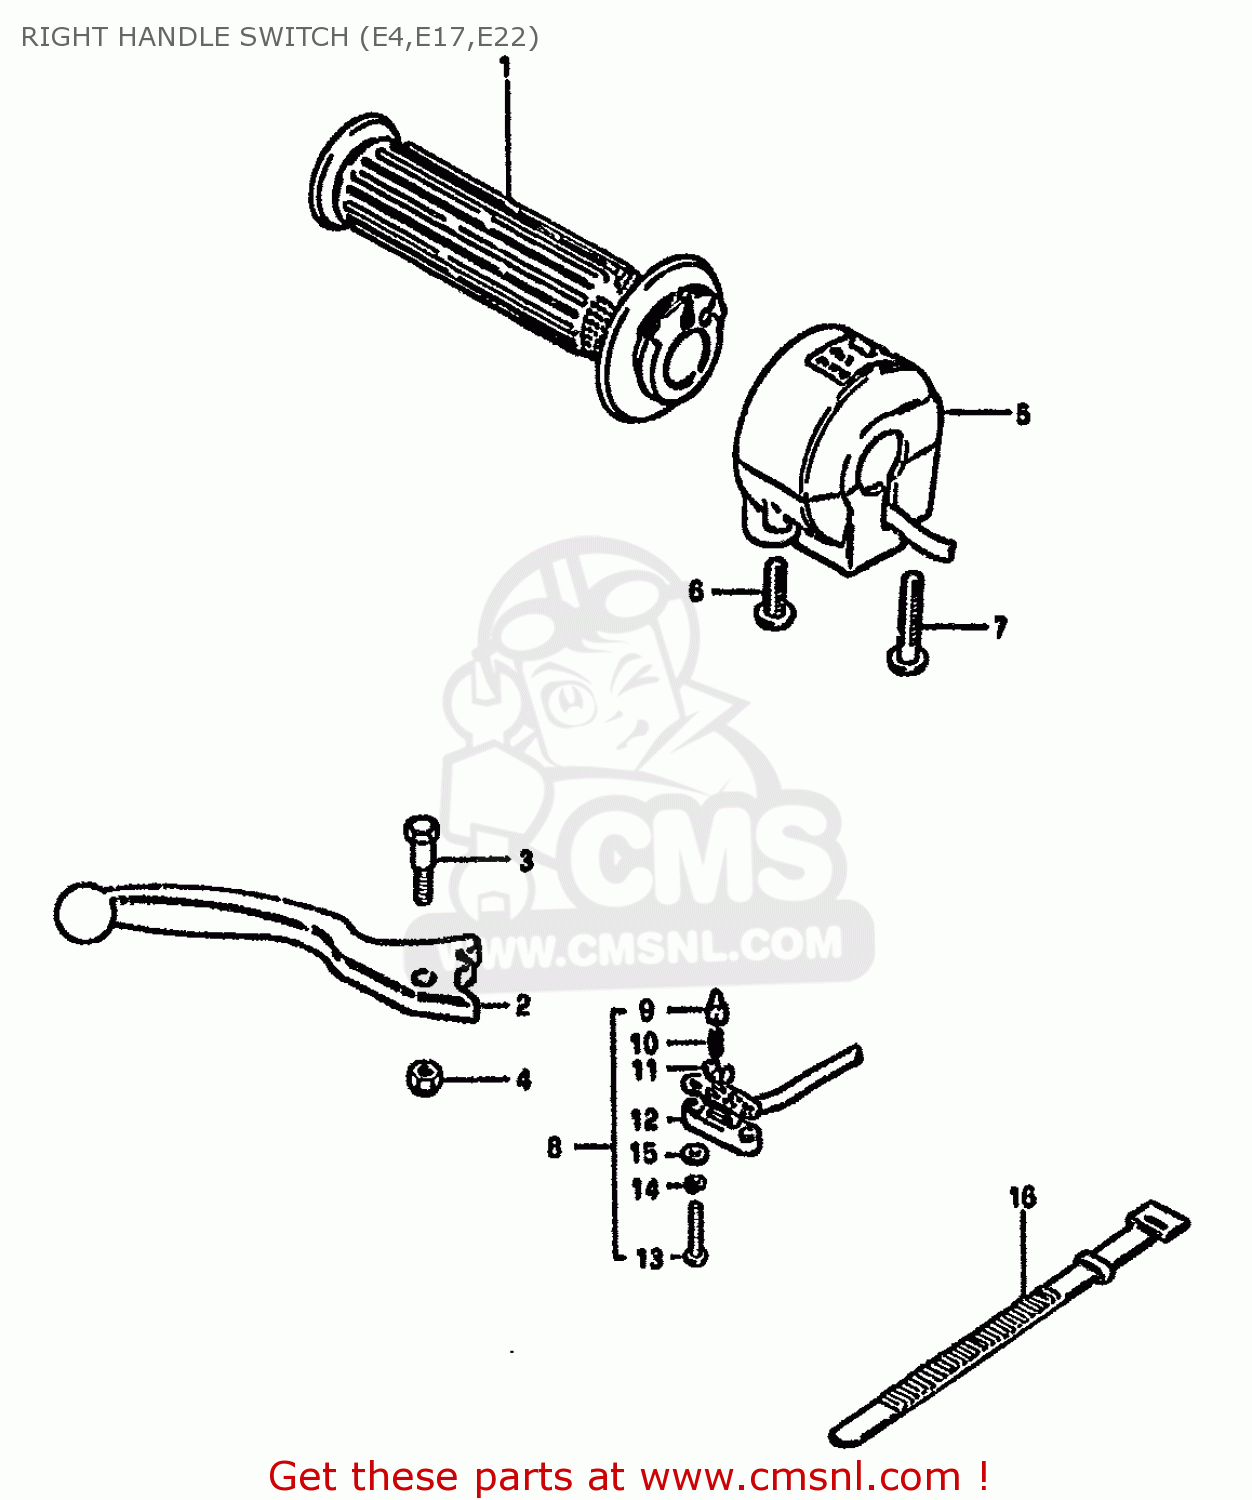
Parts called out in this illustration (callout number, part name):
1	GRIP,THROTTLE
2	LEVER,BRAKE
3	BOLT
4	NUT 6MM
5	SWITCH ASSY, HANDLE RH
6	SCREW
7	SCREW
8	SWITCH ASSEMBLY
9	HOLDER
10	SPRING
11	PLATE
12	COVER,FR BK TERMINAL BASE
13	SCREW
14	LOCK WASHER
15	WASHER
16	CLAMP(L:120)
